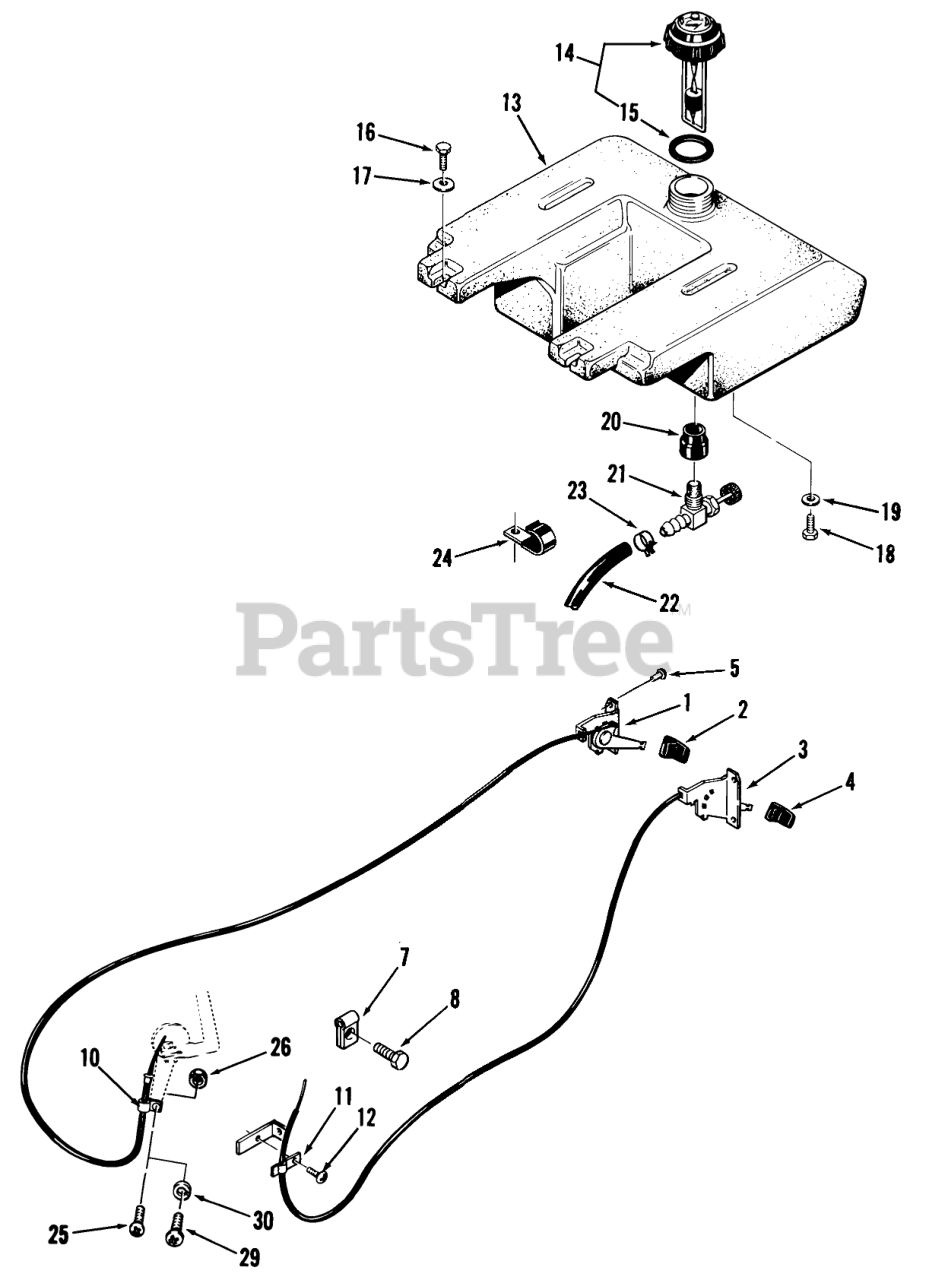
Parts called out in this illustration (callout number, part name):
1	CONTROL-THROTTLE
2	KNOB-THROTTLE
3	CONTROL-CHOKE
4	KNOB-CHOKE
5	RIVET-4
7	THROTTLE CONTROL CLP
8	Screw
10	Clip
11	CLAMP-CABLE
12	SCREW
13	TANK-FUEL
14	ASSY-GAUGE CAP
15	GASKET-GAS CAP
16	Bolt
17	Washer
18	Bolt
19	Lockwasher
20	BUSHING
21	VALVE-FUEL
22	Fuel Line
22	Fuel Line C-85 Only
23	Clamp
24	CLIP
25	Screw
26	Nut
29	Screw
30	Washer
